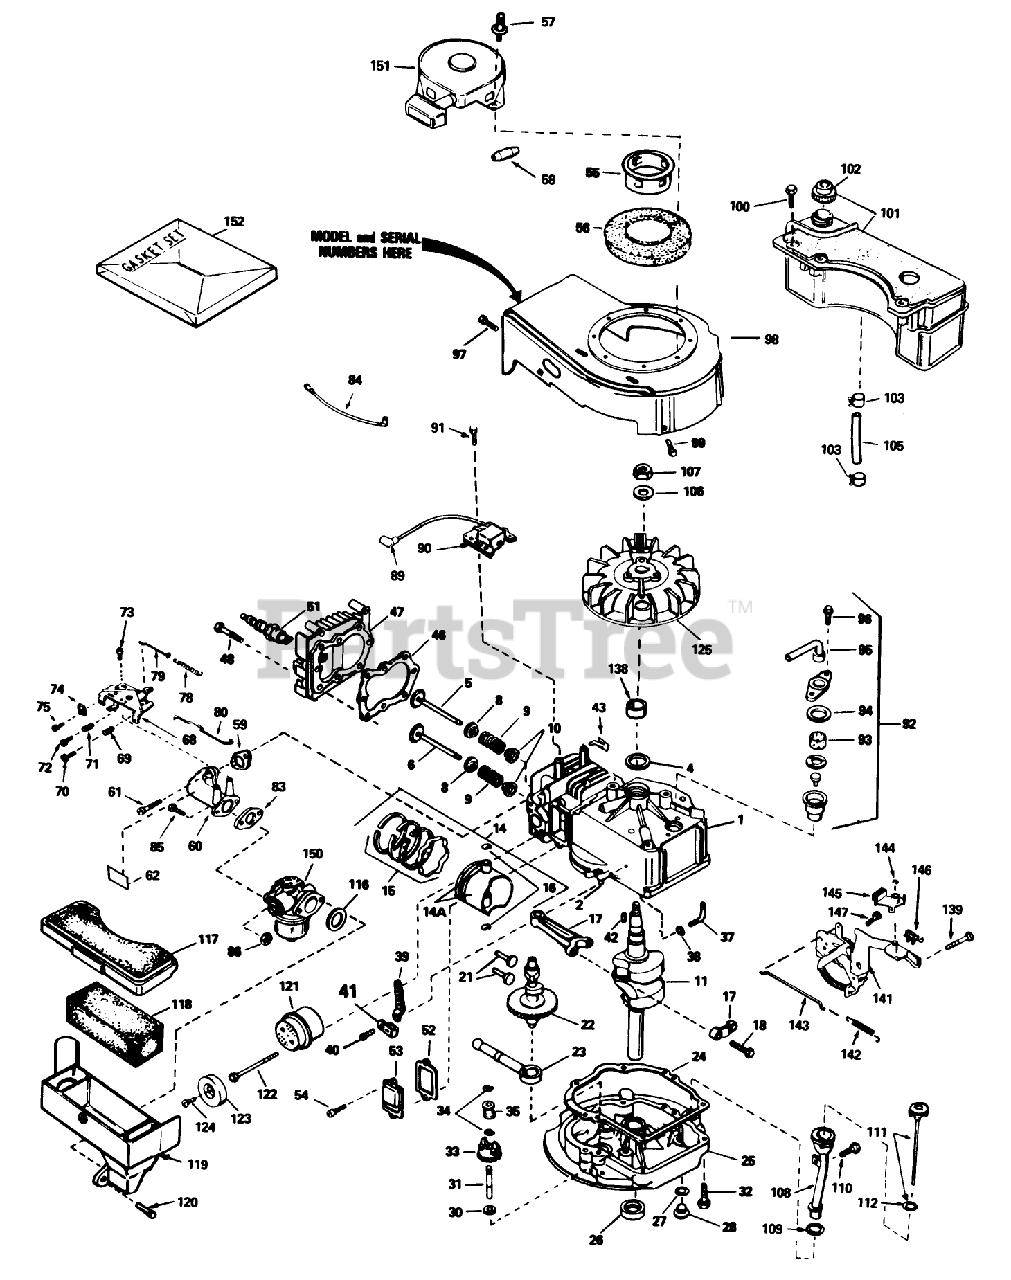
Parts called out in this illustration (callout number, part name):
1	Cylinder Assembly (Incl. Ref. #2, 4, 94 96)
2	Pin-Dowel
4	Seal-Oil
5	Valve, Intake (Std.) (Incl. Ref. #40)
5	Valve, Intake (1/32" oversize)(Incl. No. 40)
6	Valve, Exhaust (Std.)(Incl. No. 40)
6	Valve, Intake (1/32" oversize)(Incl. No. 40)
8	Cap-Upper Valve Spring
9	Spring-Valve
10	Cap-Valve, Spring
11	Crankshaft
14	Piston-Pin Ring Assy. (Std.)(Incl. Ref. #14A, 15 16)
14	Piston-Pin Ring Assy. (.010 oversize)(Incl. Ref. #14A, 15 16)
14	Piston-Pin Ring Assy. (.020 oversize)(Incl. Ref. #14A, 15 16)
14A	Piston Pin Assy. (Std)(Incl. Ref. #16)
14A	Piston Pin Assy. (.010 oversize) (Incl. Ref. #16)
14A	Piston Pin Assy. (.020 oversize) (Incl. Ref. #16)
15	Piston Ring Set Std.
15	Piston Ring Set .010 O.S.
15	Piston Ring Set .020 O.S.
16	Ring-Retaining, Piston Pin
17	Rod Assy., Connecting (Incl. Ref. #17)
18	Bolt-Rod, Connecting
21	Lifter-Valve
22	Camshaft(Mech.Comp. Release)
23	Oil Pump ASM
24	Gasket, Mounting
25	Flange Assy.-Mounting (Incl. Ref. #26, 27, 28 31)
26	Seal Oil
27	Gasket-Oil Drain
28	Plug Oil Drain
30	Washer-Flat
31	Shaft-Governor
32	Screw (1/4-20 x 1-1/4)
33	Governor Gear ASM
34	Ring-Retaining
35	Spool-Governor
37	Rod, Governor (Incl. No. 36)
38	Washer-Flat
39	Governor Lever
40	Screw
41	Clamp-Lever, Governor
42	Key-Flywheel
43	Clip-Wire
46	Gasket-Cylinder Head
47	2025A67 ADD.ASSEMBL
48	Screw (5/16-18x1-1/2)
51	Plug, Spark (Autolite 458, Champion J-19LM or equiv.)
52	Gasket-Breather
53	Cover-Valve
54	Screw
55	Cup-Starter
56	Screen-Starter
57	Pop Rivet (Can be purchased locally)
58	Retainer-Starter Rope
59	Gasket-Intake
60	Pipe-Intake (Incl. Ref. #59)
61	Screw (1/4-20 x 1)
62	Decal-Primer
68	51089 SUPP TO MANUA
69	61709/GIL1515A/95-5
70	Screw
71	Spring-Compression
72	Screw
73	Screw (10-24 x 9/16)
74	Conduit
75	Screw (10-32 x 3/8)
78	Spring Governor
79	2035A67 ADD.ASSEMBL
80	Link-Throttle
83	Gasket
84	Ground Wire
86	Nut and Lock Washer (1/4-28)
89	Cover-Spark Plug
90	Solid State
91	Screw
92	Breather Assy. (Incl. Ref. #46 thru 51)
93	Element-Breather
94	Gasket-Breather
95	Tube, Breaker
96	Screw (10-24 x 9/16)
97	Screw (10-24 x 9/16)
98	Housing-Blower
99	Screw (1/4-20 x 1/2)
100	Screw (10-32 x 35/64)
101	Tank Assembly-Fuel (Incl. Ref. #102)
102	Cap-Fuel
103	Clamp-Line, Fuel
105	Line-Fuel
106	Washer-Belleville
107	Nut-Flywheel
108	Tube-Oil Fill
109	Gasket
110	Screw (10-32 x 1/2)
111	Dipstick-Oil (Incl. Ref. #112)
112	O-Ring
116	Gasket-Cleaner, Air
117	Cover Air Cleaner
118	Filter-Air Cleaner
119	Body Air cleaner
120	Screw
121	Muffler (Incl. Ref. #122)
122	Screw
123	Cover-Muffler
124	Screw
125	Flywheel
138	Spacer
139	Screw (1/4-20 x 3/8)
141	Bracket Assy.
142	Spring-Extension
143	Link-Control
144	Ring-Retaining
145	Lever-Brake
146	Terminal
147	Screw-Hex. Hd.
150	Carburetor (Incl. Ref. #83)
151	tarter-Rewind
152	Gasket Set
